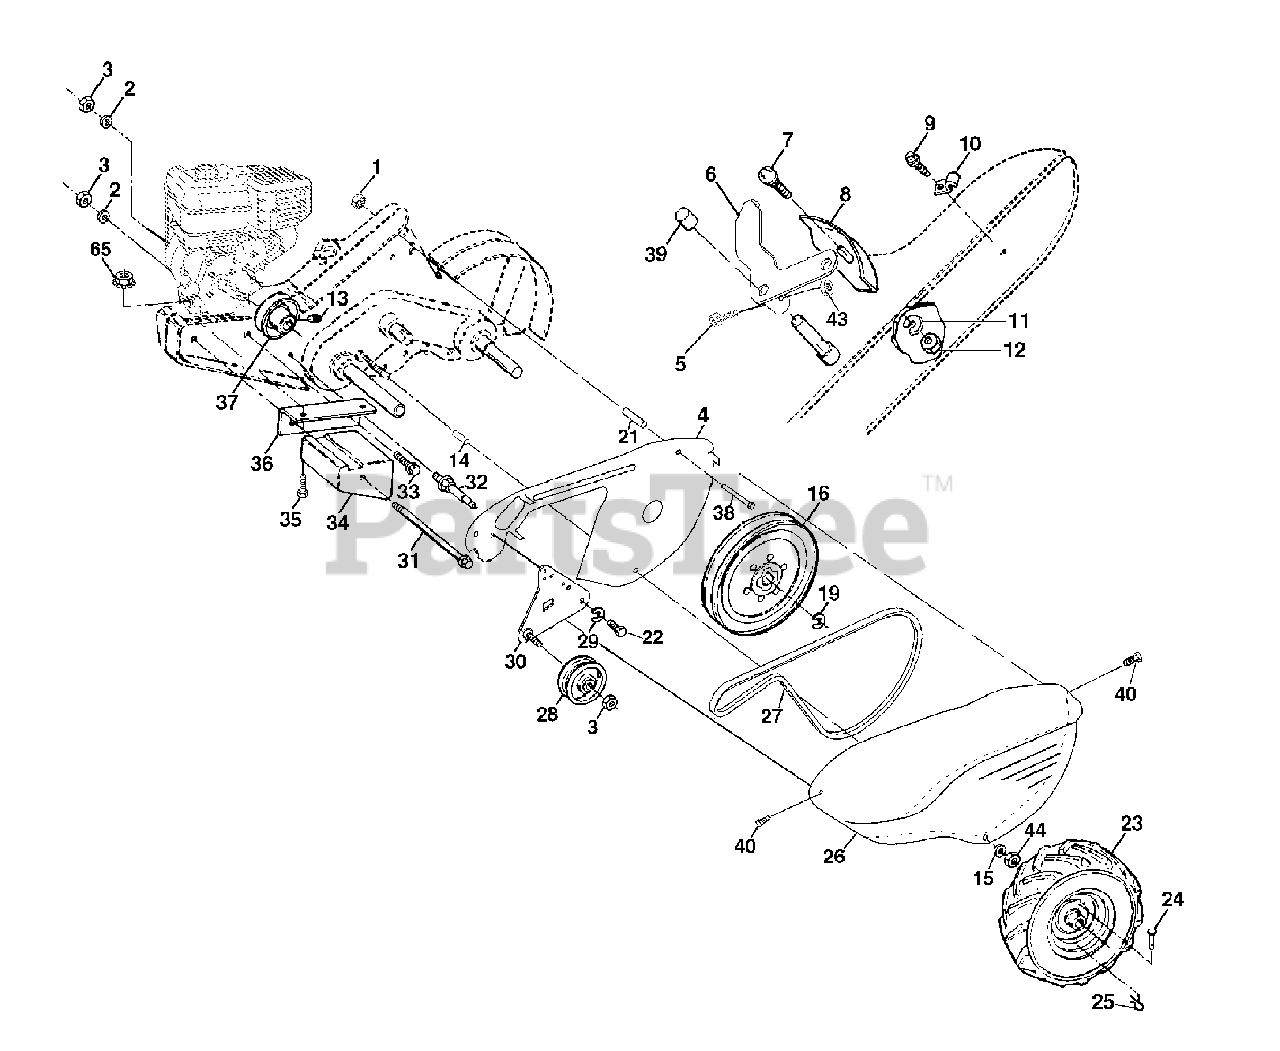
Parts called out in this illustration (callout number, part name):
1	Nut, Keps 5/16-18
2	Washer, Lock 3/8
3	Nut, Hex 3/8-16
4	Shield, Inner Belt Guard
5	Screw, Shift Lever
6	Lever, Shift
7	Bolt, Carriage 1/4-20 x 1/2 Gr. 5
8	Plate, Shift Indicator
9	Screw, Hex, Washer Head, Slotted #10-24 x 1/2
10	Clip
11	Washer, Lock 1/4
12	Nut, Hex 1/4-20
13	Screw, Set, Hex 5/16-18 x 3/8
14	Spacer, Split 0.327 x 0.42 x 1.220
15	Washer 11/32 x 11/16 x 16 Ga.
16	Sheave, Transmission
19	Ring, Retainer
21	Spacer, Split 0.327 x 0.42 x 2.09
22	Bolt, Fin Hex 5/16-24 x 1/2
23	Tire
23	Tire Valve
24	Rivet, Drilled
25	Clip, Hairpin
26	Guard, Belt
27	Belt, V
28	Pulley, Idler
29	Ring, Klip
30	Bracket, Idler
31	Bolt, Hex 5/16-16 x 12
32	Shaft, Idler Arm
33	Bolt, Hex 3/8-16 x 1
34	Counterweight, L. H.
35	Bolt, Hex 5/16-18 x 1-1/2
36	Bracket, Reinforcement, L. H.
37	Sheave, Engine
38	Bolt, Fin Hex 5/16-18 x 2-3/4
39	Cap, Plunger
40	Screw Hex Wsh Slt # 10-24 x .50
43	Nut, Lock #10-24
44	Nut, Lock 5/16-18
65	Nut, Lock Hex Flange
